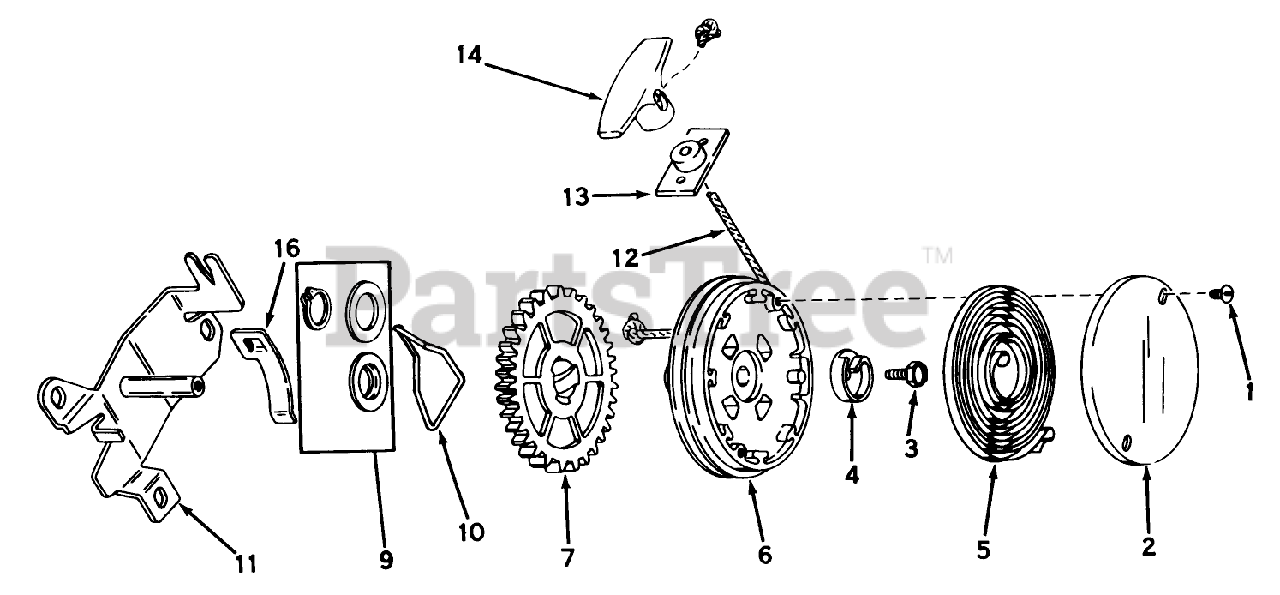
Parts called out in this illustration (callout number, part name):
1	Screw, Cover
2	Cover, Spring
3	Screw, Hex Washer Head
4	Hub Spring
5	Spring, Rewind
6	Pulley Assy. (Incl. No. 9)
7	Gear
9	Kit, Thrust Wash. & Snap Rg.
11	Bracket Assy. Mounting
12	Rope, Starter
13	Bracket Assy.
14	Handle-Starter
16	Clip Rope
